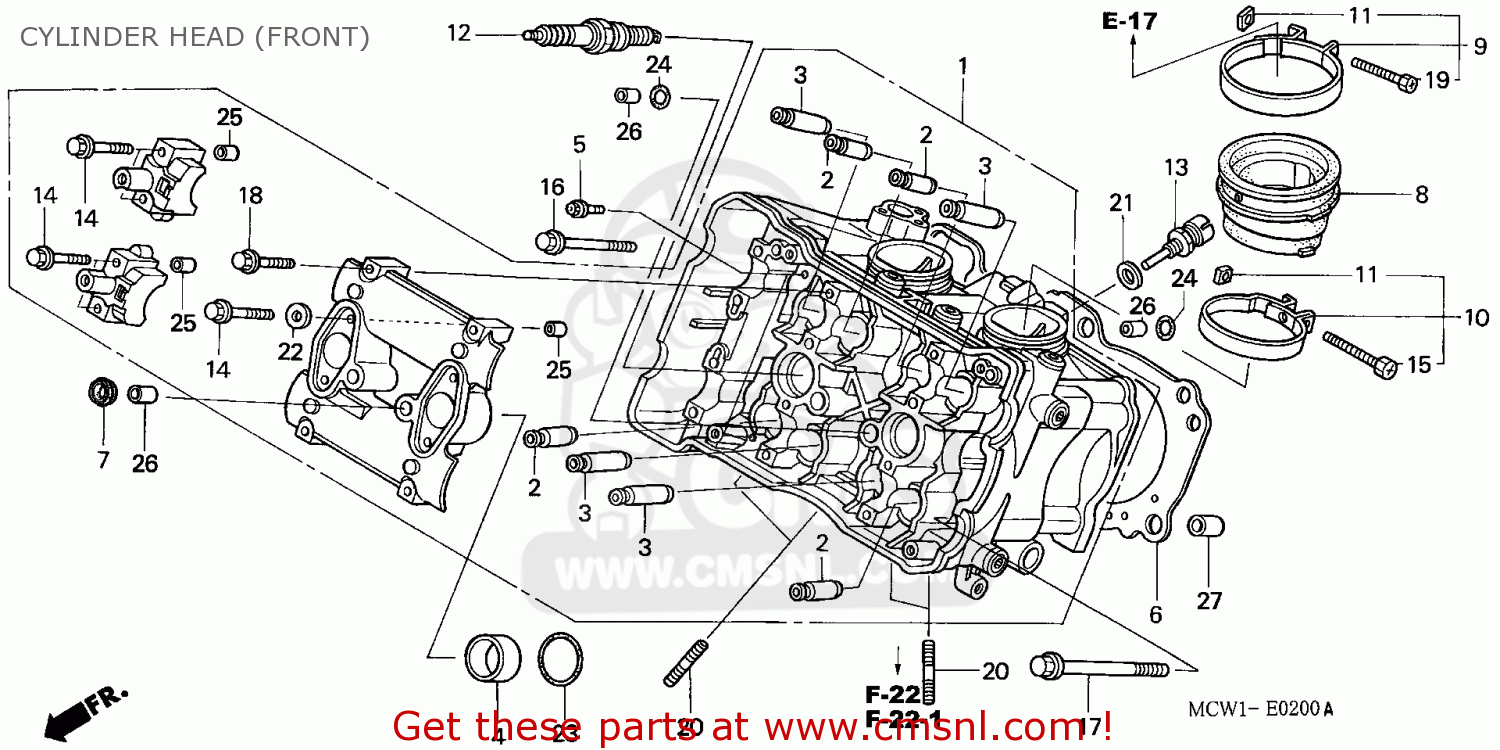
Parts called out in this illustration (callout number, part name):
1	HEAD ASSY,FRONT
2	GUIDE,VALVE 0SZ
3	GUIDE,VALVE B OSZ
4	COLLAR,25MM
5	ORIFICE BOLT
6	GASKET,CYLINDER H (NAS)
7	GASKET C,HEAD COV (NAS)
8	INSULATOR,THROT B
9	BAND,INSULATOR
10	BAND B,INSULATOR
11	NUT,SQUARE,5MM
12	SPARK PLUG,IMR9B-
13	SENSOR ASSY,TW
14	BOLT,FLANGE,6X45
15	BOLT,RECESSED,5X3
16	BOLT,FLANGE,NSHF,
17	BOLT,WASH 9X100
18	BOLT,FLANGE 6X37
19	BOLT,RECESSED,5X2
20	BOLT STUD,6X22
21	WASH,SPECIAL,12MM
22	WASHER,SEALING,6.
23	O RING,24.5X1.9
24	O-RING, 9.8X1.9
27	DOWEL,PIN,12X20
